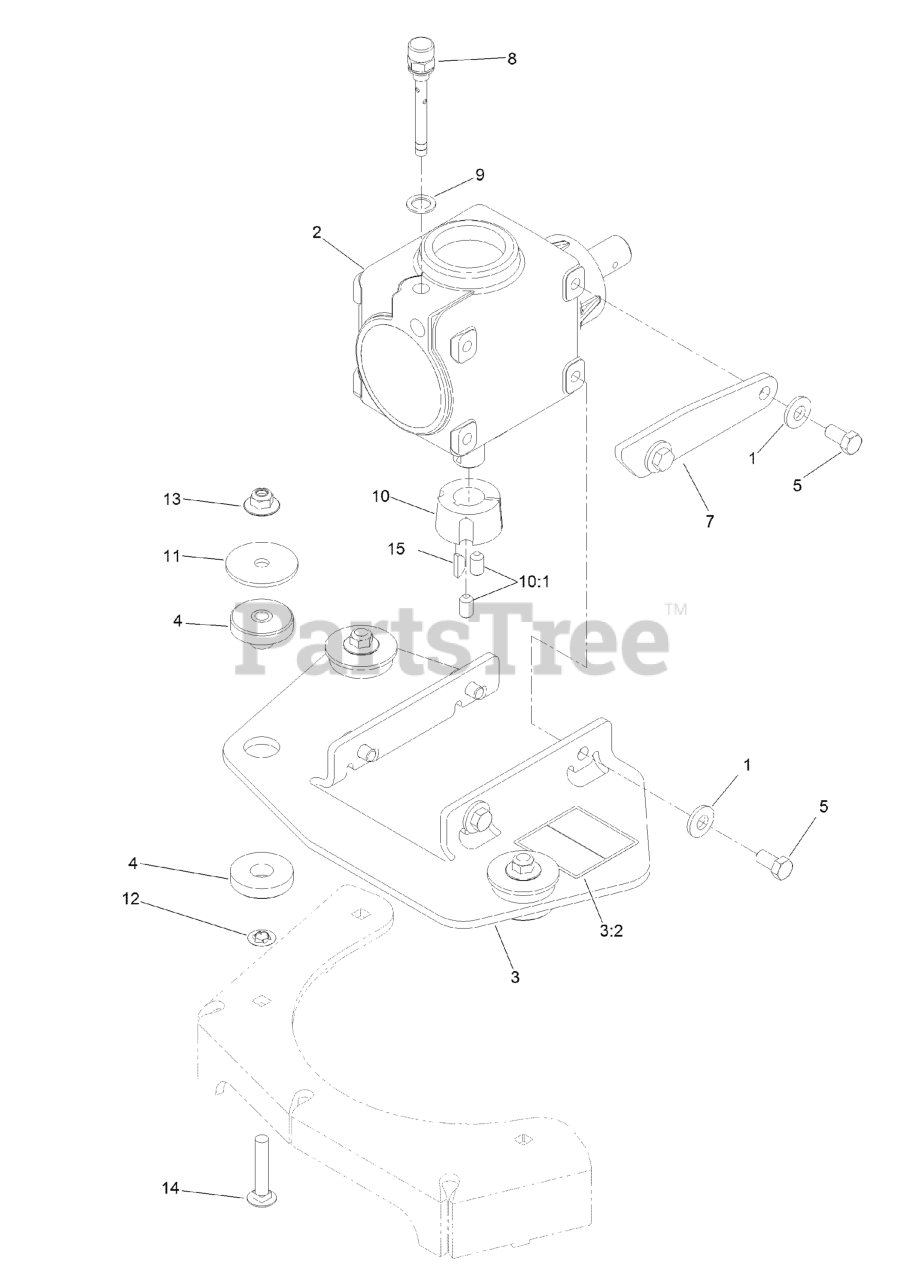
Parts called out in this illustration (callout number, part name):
1	WASHER-BELLEVILLE
2	GEARBOX ASM
3	MOUNT-GEARBOX
3:2	DECAL-HAZARD, ENTANGLEMENT
4	MOUNT-ISO
5	SCREW-HH
7	STOP-GEARBOX
8	PLUG-BREATHER
10	BUSHING-TAPERLOCK
10:1	SCREW-SET
11	WASHER-FLAT
12	NUT-PUSH
13	Nut-Nyloc 3/8-16 Flg
14	SCREW-CARR
15	KEY-WOODRUFF
